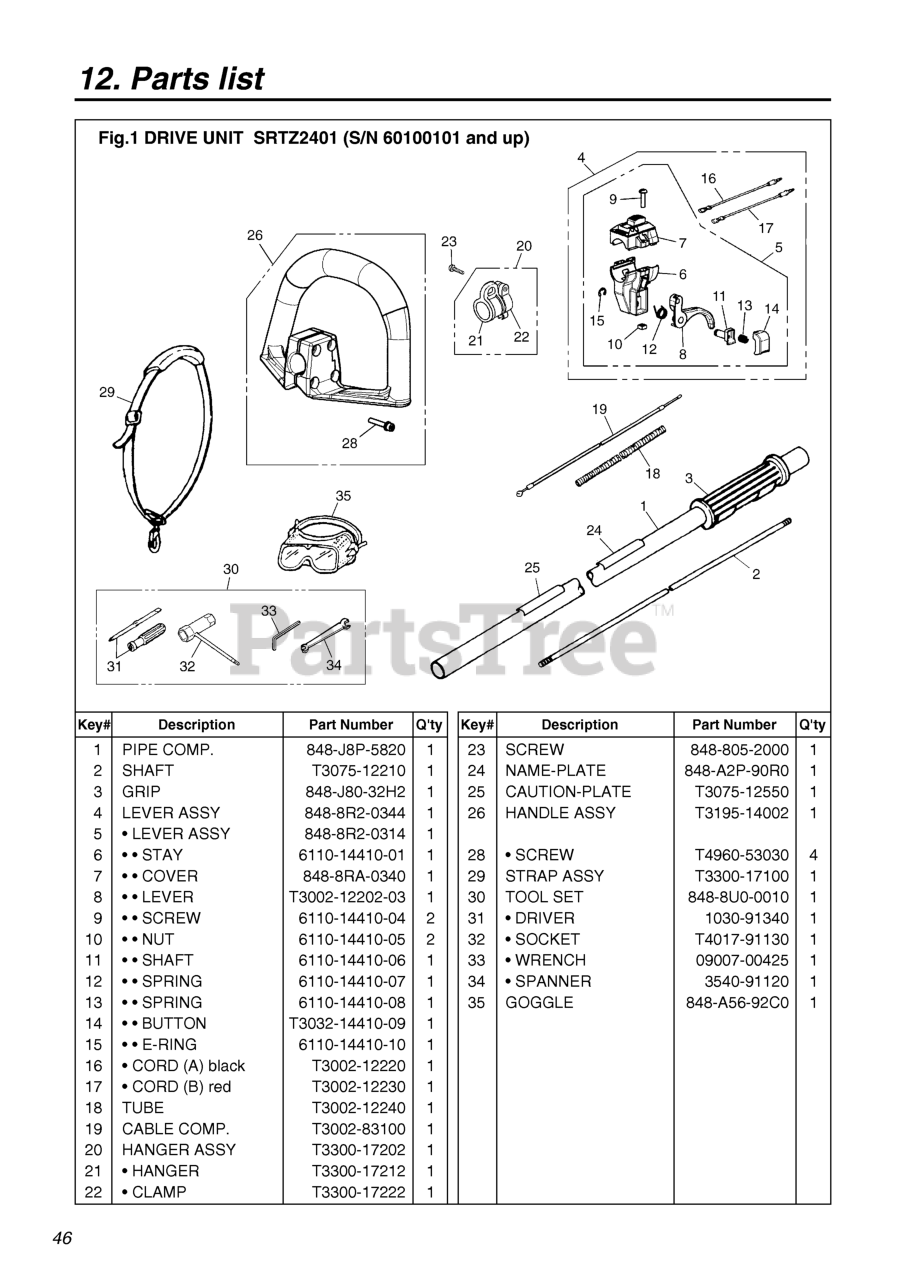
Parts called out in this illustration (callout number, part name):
1	PIPE COMP
2	SHAFT
3	GRIP
4	LEVER ASSY
5	LEVER
7	COVER COMP. (RP. 6110-14410-02)
8	FLEX, TRIGGER
16	CORD (A), BLACK
17	CORD (B), RED
18	TUBE (RPLS 4900-72141)
19	CABLE (RPLS 5580-83100)
20	HANGER COMP.
23	SCREW
24	NAMEPLATE
25	LABEL (CAUTION)
26	HANDLE ASSY. (REPLACES -14001)
28	SCREW
29	STRAP ASSY.
30	TOOL-SET
31	SCREWDRIVER
33	WRENCH (TOOL)
34	SPANNER, 8 X 10 (RPLS 2540- )
35	GOGGLE
